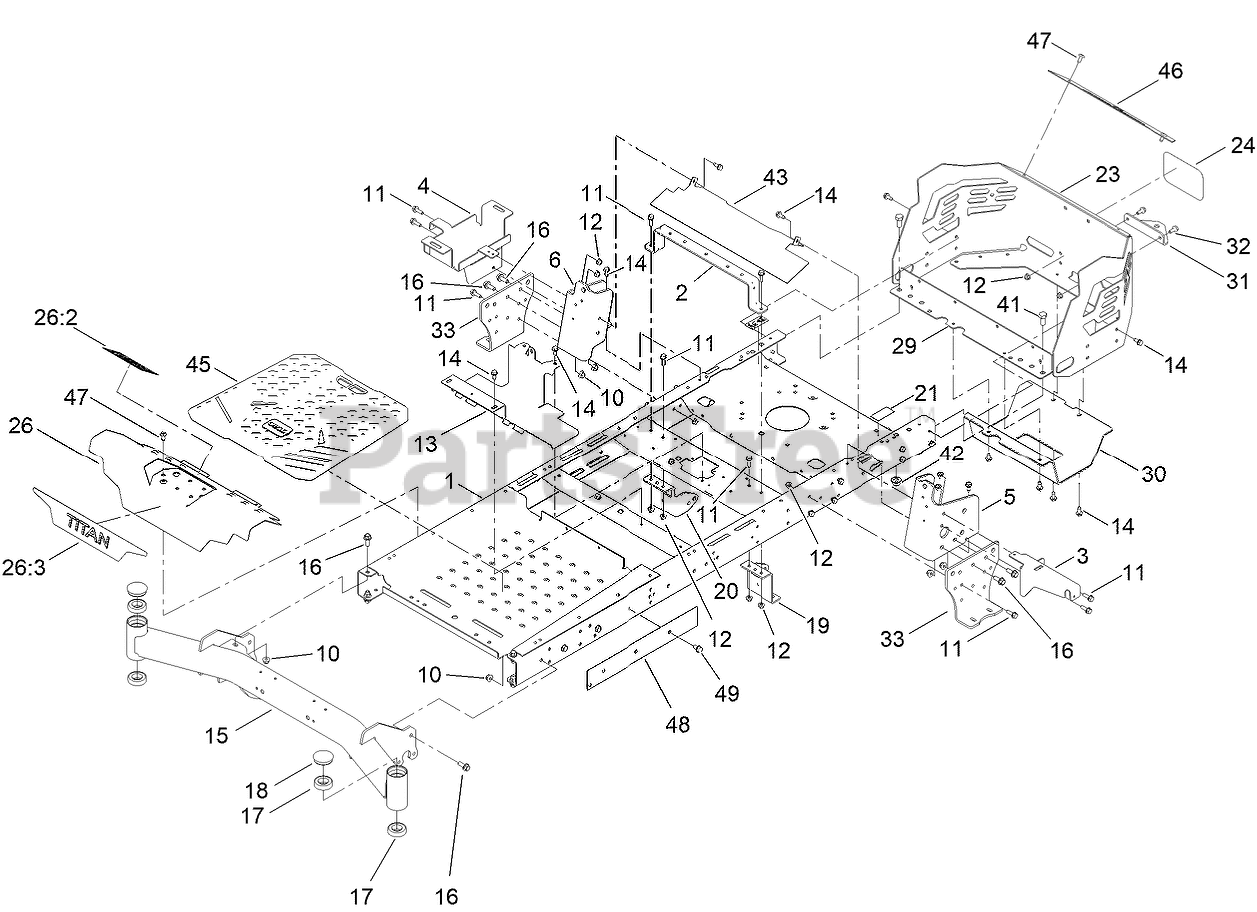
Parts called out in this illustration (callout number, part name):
1	FRAME ASM
2	BRACE-SEAT, REAR (WIDE)
3	BRACKET-SUPPORT, POD (LH)
4	TRAY-BATTERY
5	BRACKET-MOUNTING, LH
6	BRACKET-MOUNTING, RH
10	NUT-HF, NI
11	SCREW-HHF
12	NUT-HF, NI
13	BRACKET-MOUNT
14	SCREW-HWHTF
15	FRONT AXLE ASM
16	SCREW-HHF
17	BEARING-BALL
18	CAP-GREASE
19	MOUNT-HYDRO, FRONT (LEFT)
20	MOUNT-HYDRO, FRONT (RIGHT)
21	DECAL-BYPASS
23	GUARD-ENGINE
24	DECAL
26	FOOTREST-TITAN
26:2	DECAL-DANGER
26:3	DECAL-TITAN
29	CROSSMEMBER-REAR, WIDE
30	GUARD-MUFFLER
31	BRACKET-HITCH
32	SCREW-HHF
33	MOUNT-HYDRO
41	SCREW-HH
42	NUT-LOCK
45	FLOOR MAT
46	TRIM-GUARD, ENGINE
48	PLATE-FRAME
49	SCREW-HWHTF
